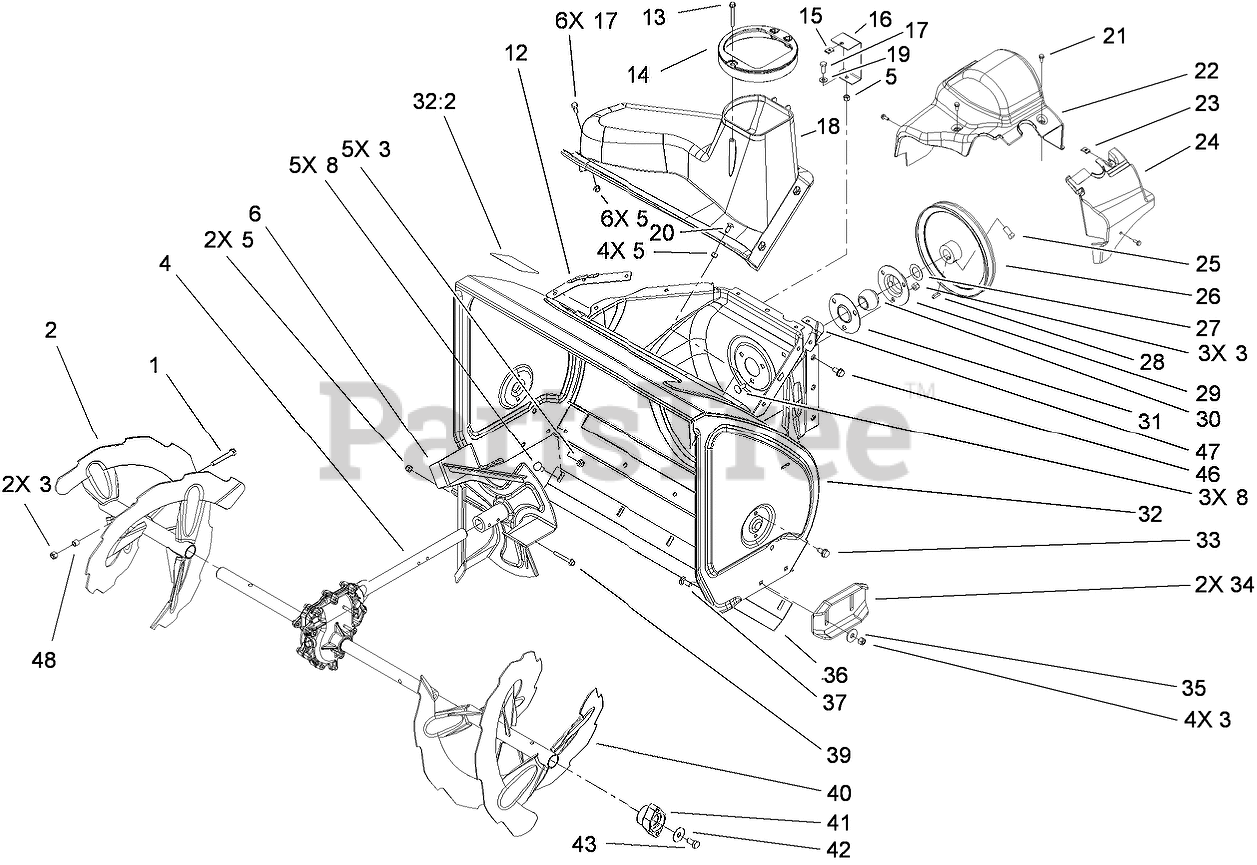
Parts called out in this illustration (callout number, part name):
1	SCREW-HH
2	RH AUGER ASM
3	NUT-LOCK, NI
4	26 INCH AUGER GEARCASE ASM
5	NUT-LOCK, NI
6	IMPELLER ASM
8	SCREW-CARR
12	SEAL-FLANGE, COVER
13	SCREW-PLASTITE
14	GUIDE-CHUTE
15	NUT-SPEED, U-TYPE
16	BRACKET-COVER, CLIP NUT
17	SCREW-HH
19	WASHER-FLAT
20	BOLT-CARR
21	SCREW-HWH
22	COVER-BELT
23	NUT-SPEED
24	COVER-EXTENSION, BELT
25	SCREW-SET, SQH
26	PULLEY-IMPELLER
27	WASHER-THRUST
28	KEY-WOODRUFF
29	FLANGE-CUP, BEARING
30	BEARING-BALL
31	FLANGE-CUP, BEARING
32	HOUSING-AUGER, 26 INCH
32:2	DECAL-WARNING, AUGER
33	SCREW-HWHTF
35	WASHER
36	SCRAPER-FIXED
37	SCREW-CARR
39	SCREW-HHF
40	LH AUGER ASM
41	BEARING-AUGER
42	WASHER
43	SCREW-HH
46	SCREW-HWHTF
48	SPACER
